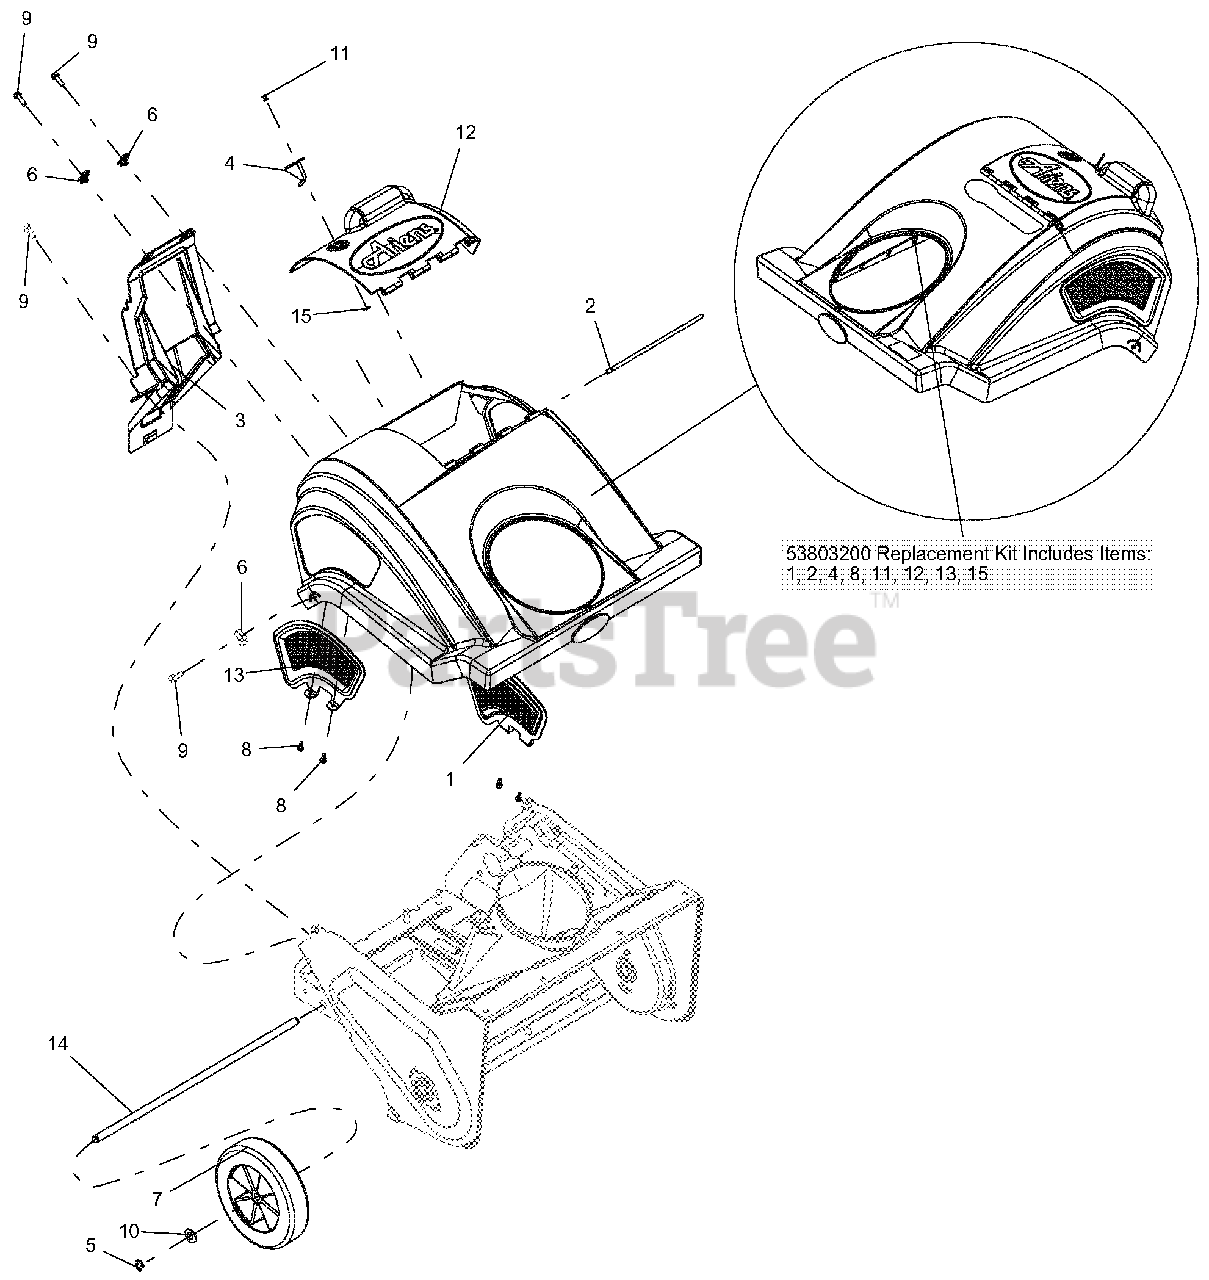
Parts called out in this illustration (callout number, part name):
1	VENT, COVER LEFT
2	ROD, COVER, SINGLE STAGE
3	BACK COVER, NON ELEC. START
4	TAB, LATCH
5	RG-RTNG-EXT .500X.042 (E)
6	NUT-RTNR .25-20X.56
7	WHL 7.50" .50 BORE, 1.50 HUB
8	SCR-TAP #10X.50 BOSS INDHXHD
9	BLT-HEX .25-20X.75 HWH YZ GR5
10	WSHR-FL-STL.531X1.00X.063 YWZC
11	RVT-POP .187 YZ
12	DOOR, COWEL COVER
13	RIGHT VENT, COVER
14	SHAFT, AXLE
15	WSHR-FL-STL .196X.500X.06 YZ
